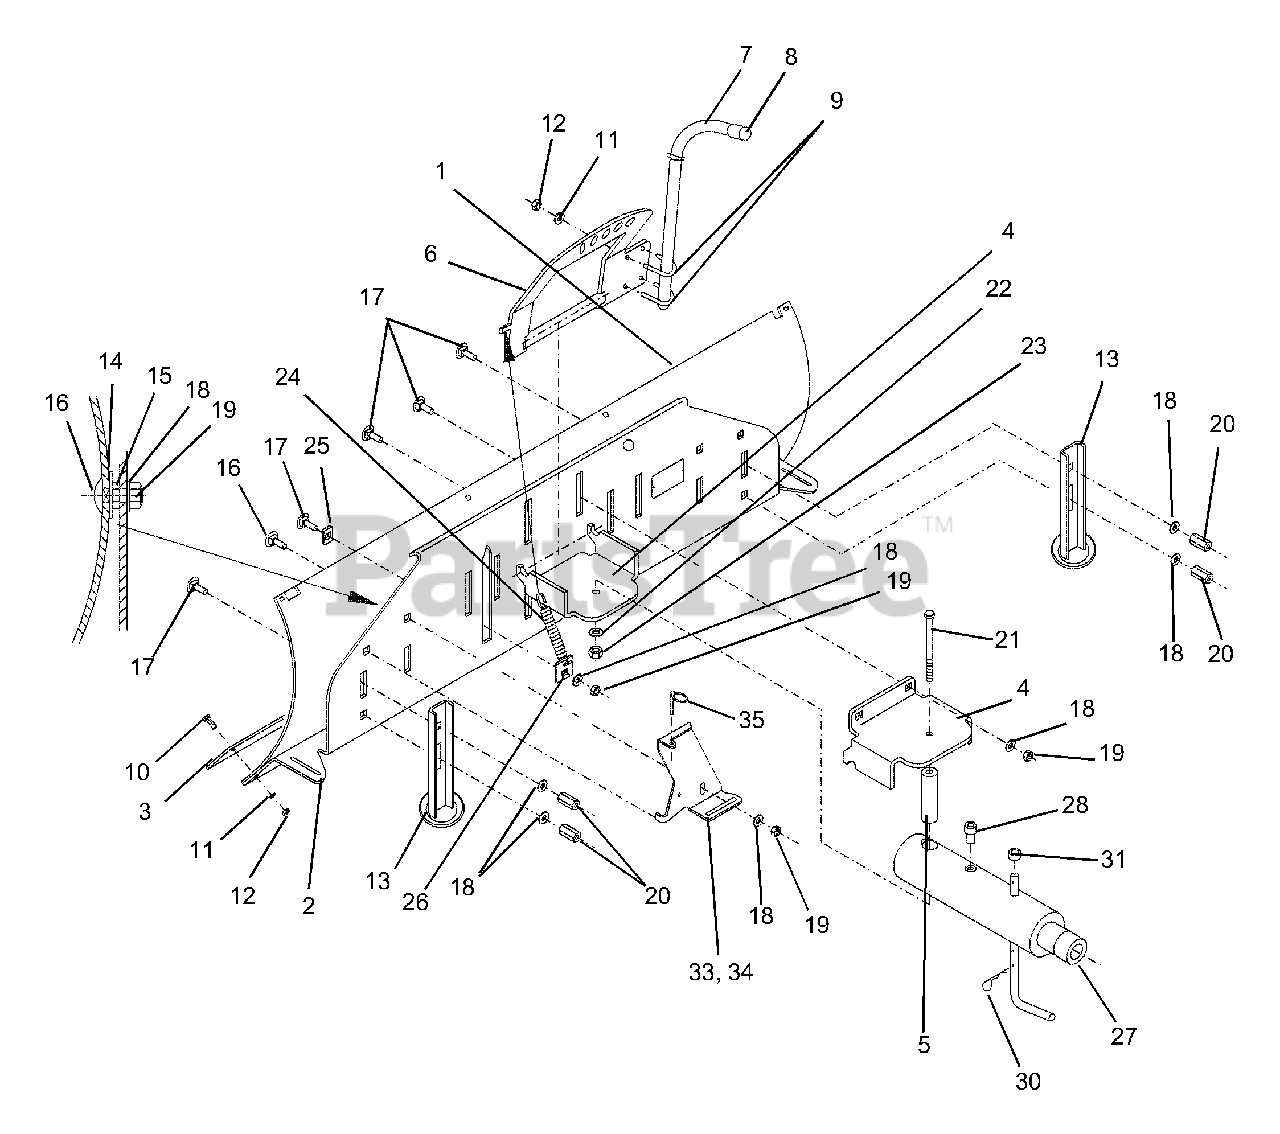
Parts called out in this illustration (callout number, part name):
1	Snow Blade, 125 cm (50 in.)
2	Sheet, 125 cm (50 in.)
3	Ploughshare
4	Plate, Connection
6	Plate, Adjusting
7	Handlebar
10	Bolt, Hex, D933 M8 x 30
11	Washer, M8
12	Nut, Hex D934 M8
14	Washer, D125 17 x 30 x 3
15	Nut, Hex D439 M12
16	Bolt, Square Neck D603 M12 x 35
17	Bolt, Square Neck D603 M12 x 30
18	Washer, M12
19	Nut, Hex D934 M12
20	Nut, Hex, D6334 M12 x 36
21	Bolt, Hex D921 M14 x 140
22	Washer, Spring 14.4 x 30.2
23	Nut, Lock D985 M14
24	Spring, Tension
25	Guide, Spring
26	Retainer, Spring
27	Arm, Support
28	Screw, Cylinder
30	Pin, Detent
31	Nut, Lock
32	Guard, Sheet Metal
33	Bracket, Left
34	Bracket, Right
35	Pin, Lynch
